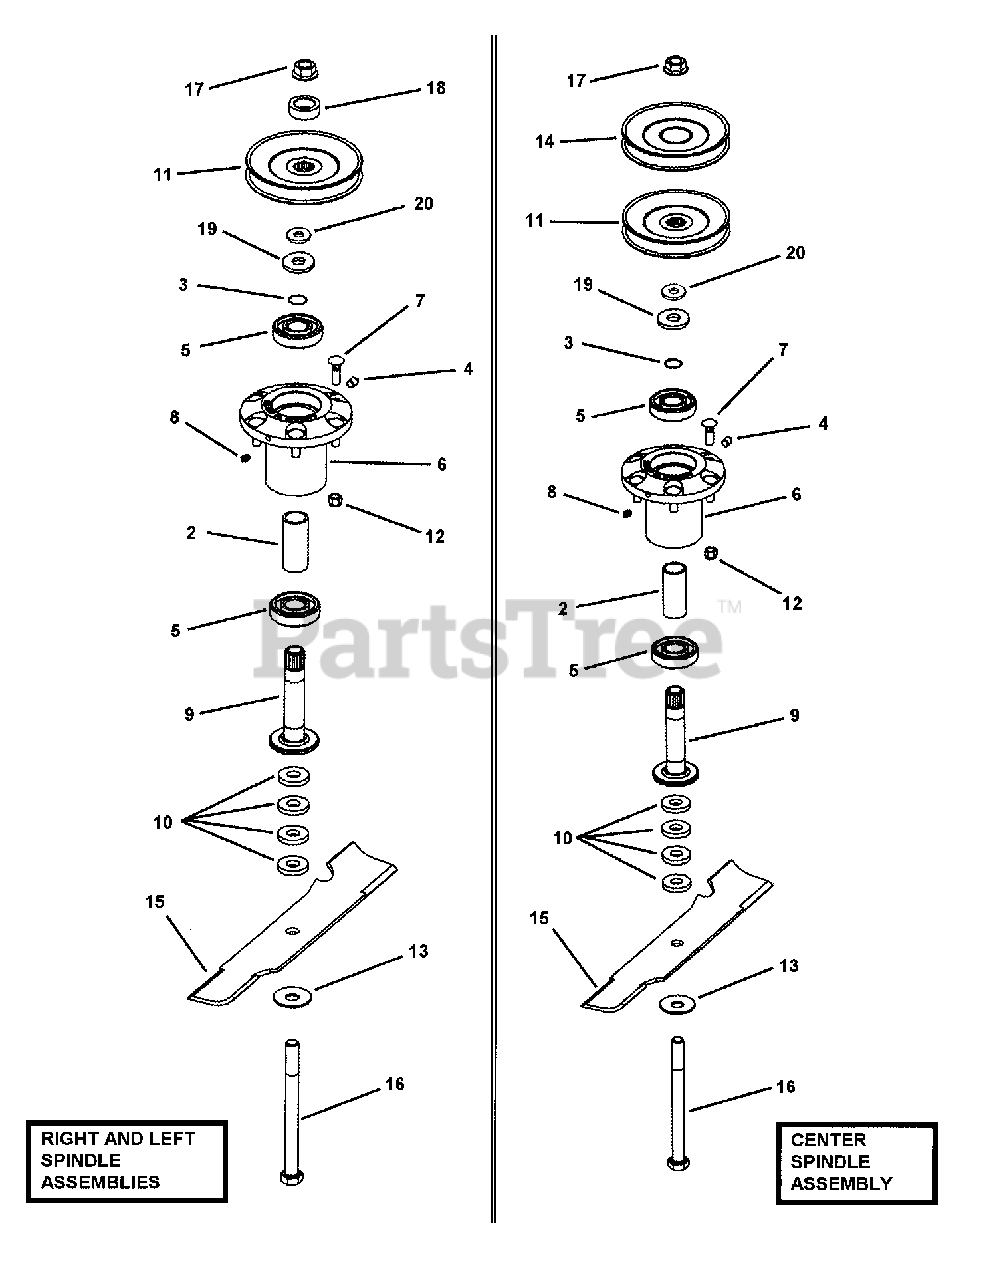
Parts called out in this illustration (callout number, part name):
2	SPACER, Bearing
3	*RING, Spindle Retaining
4	VENT, Spindle (Alemite # 321839)
5	BALL BEARING (2 per item 1, sub-assembly)
6	ASSEMBLY, Spindle Housing (includes items 4 & 8)
7	BOLT, Ribbed (3/8-16 x 1-1/4" Thread) (6 per item 1, sub-assembly)
8	FITTING, Lube (1/4-28 Special Thread Forming)
9	SHAFT, Spindle
10	SPACER, Blade
11	PULLEY, 5.75" Diameter
12	NUT, 3/8-16 Hex Nyloc (6 per spindle assembly)
13	WASHER, Beveled
14	PULLEY, Driven (48" Deck only)
14	PULLEY, Driven (52" Deck only)
14	PULLEY, Driven (61" Deck only)
15	BLADE, 16-1/2" (48" Deck only)
15	BLADE, 18" Commercial w/Extra Cut (52" Deck only)
15	BLADE, 21" (61" Deck only)
16	BOLT, 5/8-11 x 7-1/2" Hex, GR 5
17	NUT, 5/8-11 Hex Flange Lock, GR 5
18	WASHER, Spindle
19	*SEAL, Nylos
20	*WASHER
